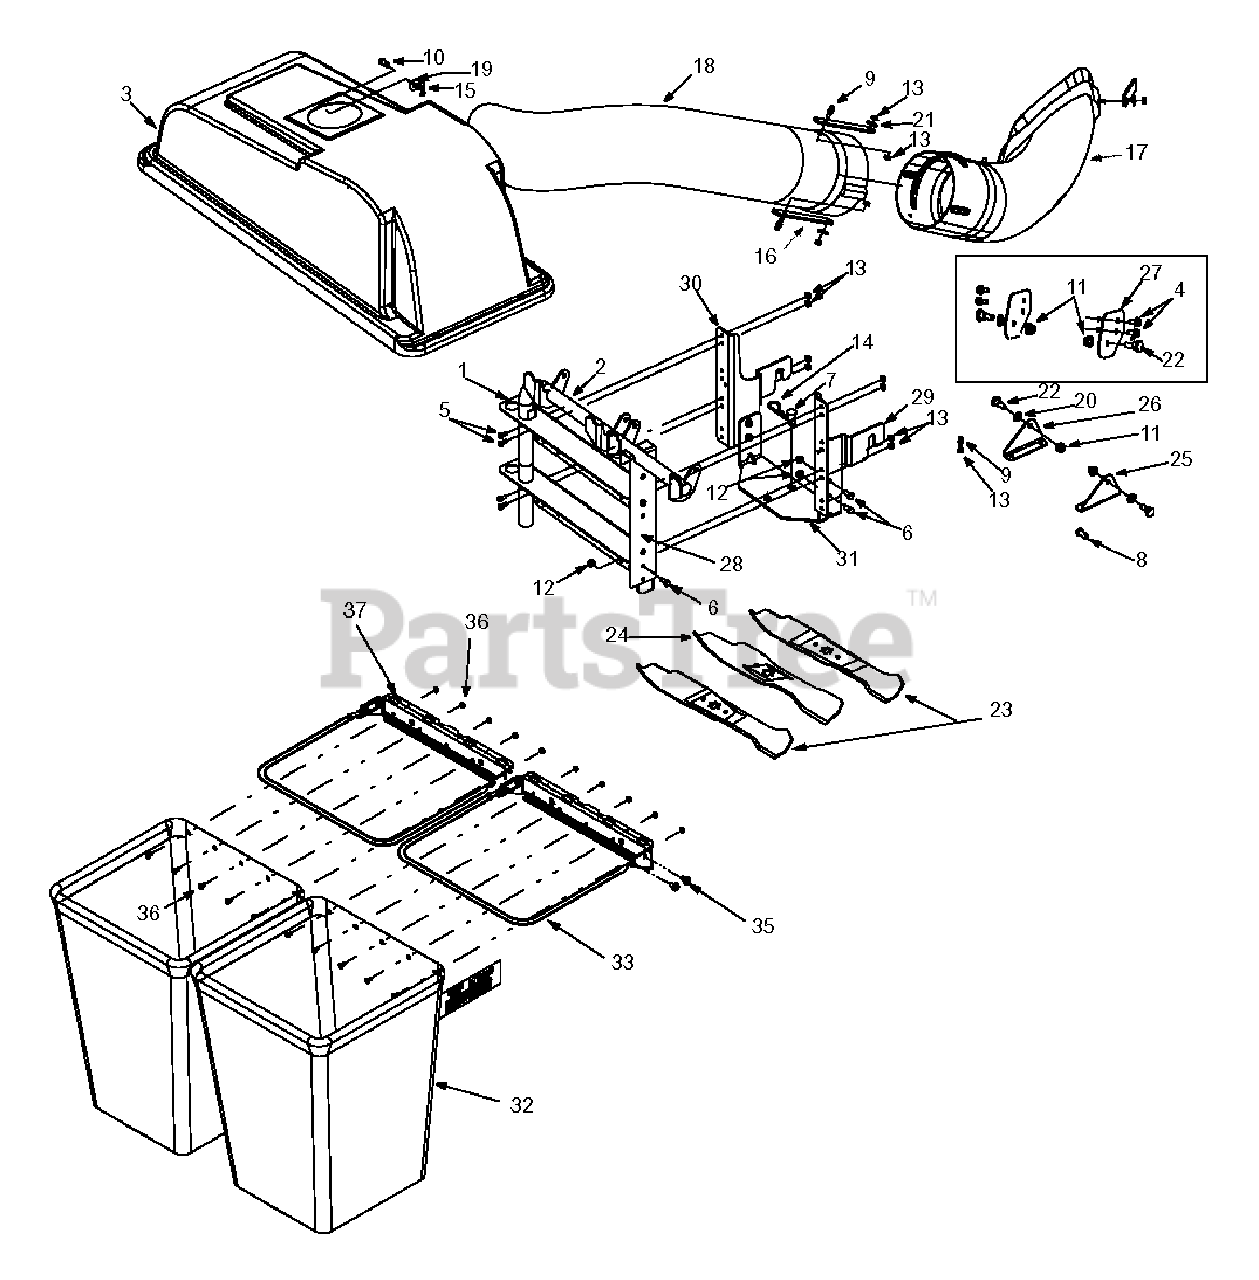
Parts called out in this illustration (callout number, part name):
3	Grasscatcher Cover Assembly
4	Self-tapping Screw 3/8-16 x 0.75"
5	Hex Screw 1/4-20 x0.620
6	Hex Screw 5/16-18 x 0.75"
7	Clevis Pin
9	Grasscatcher Pin
10	Clevis Pin
11	Lock Nut 7/16-20
12	Lock Nut 5/16-18
13	Flange Lock Nut 1/4-20
14	Hairpin Clip
15	Click Pin
16	Chute Strap
17	Discharge Chute 46"
18	Catcher Tube
19	Bell Washer
20	Bell Washer
21	Flat Washer
22	Shoulder Screw
23	Blade 16.28" Lg. (model 190-182)
24	Blade 14.88" Lg. (model 190-182)
32	Catcher Bag
34	Hex Sems Nut, #10-24
35	Self-tapping Screw, 5/16-18 x .625
36	Machine Screw, , #10-24 x .5
